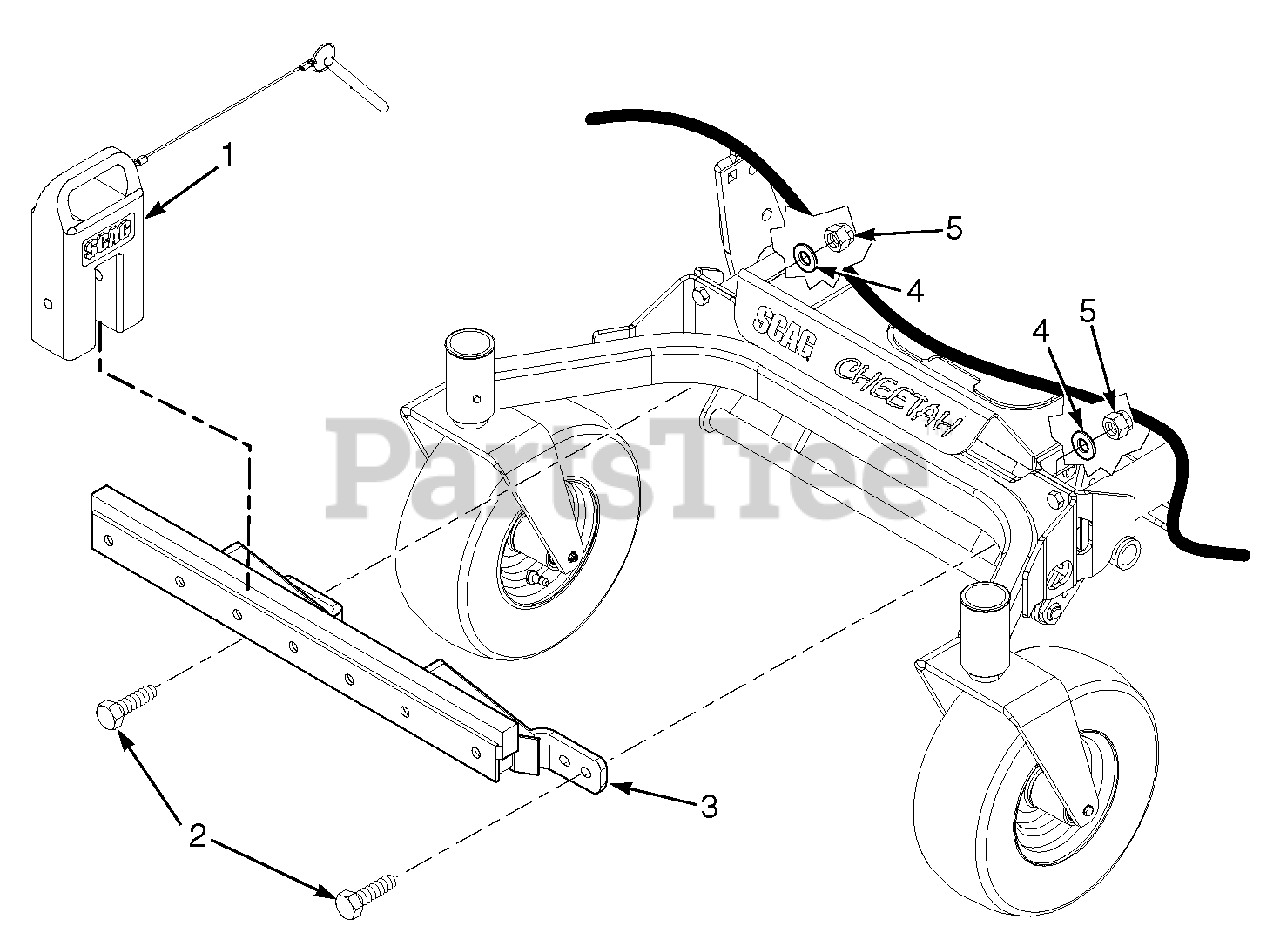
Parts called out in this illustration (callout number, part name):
1	Weight Assembly
2	Bolt, Hex Head 7/16-14 x 1-3/4"
3	Support Weldment, Weights
4	Flatwasher, 7/16-.500 x 1-1/4"
5	Nut, Elastic Stop 7/16-14
